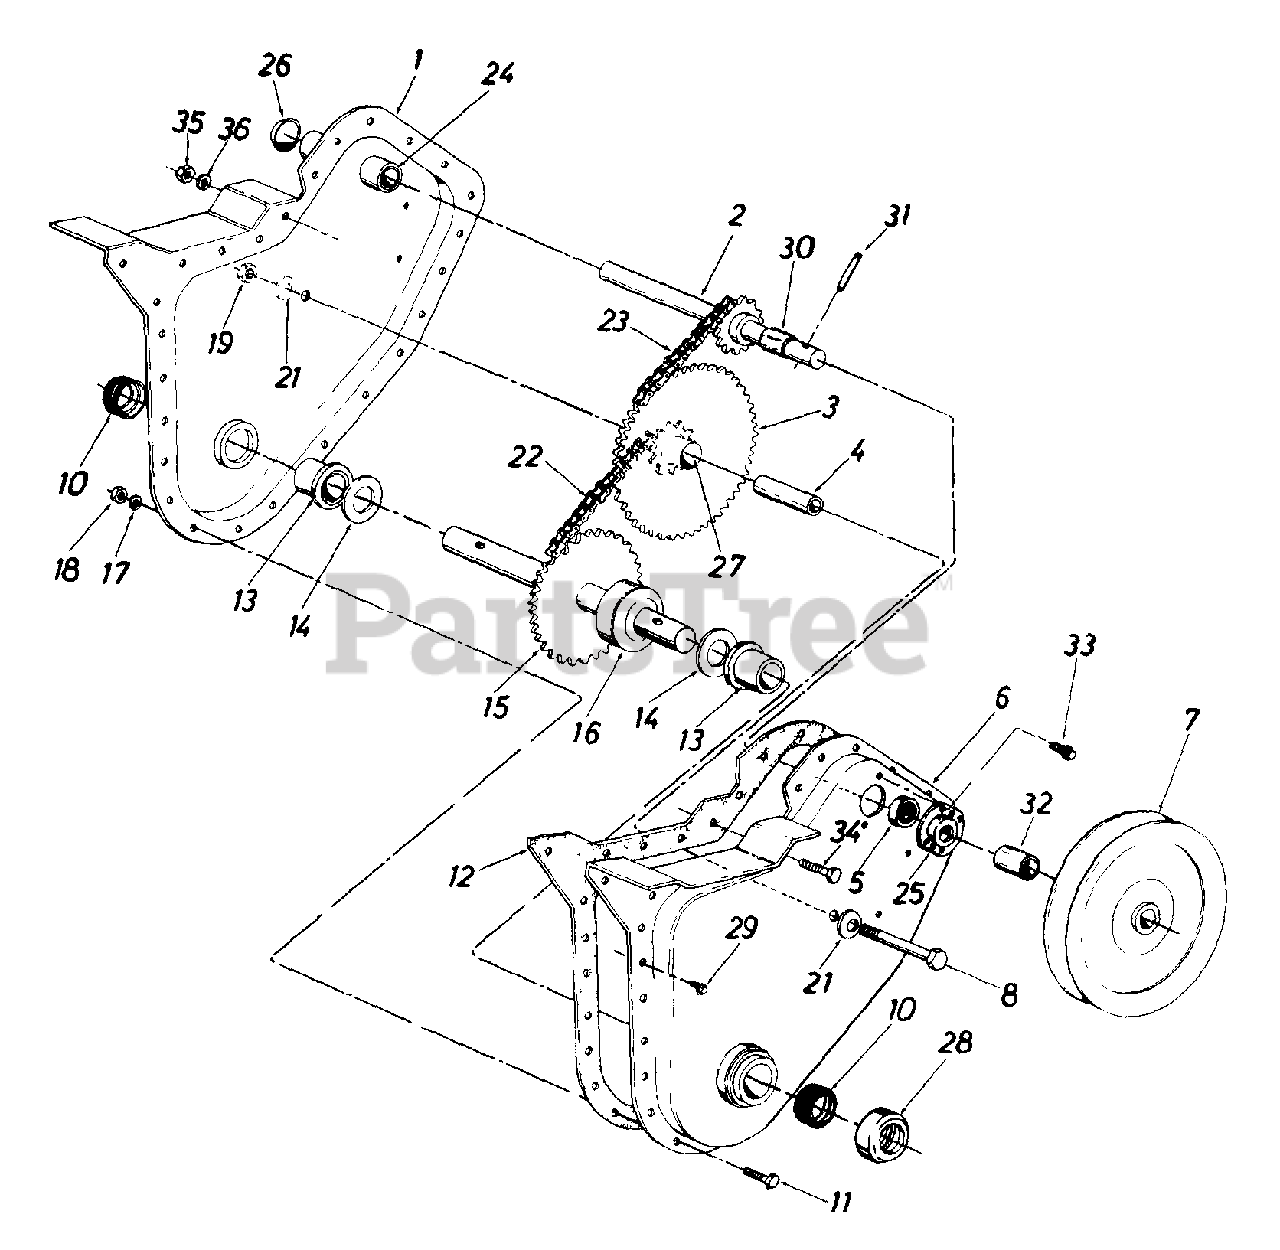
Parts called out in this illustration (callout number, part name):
1	Chain Case Ass'y.- R.H.
2	Input Shaft Ass'y.
3	Hub and Sprocket Ass'y.
4	Bearing Inner Race
5	Ball Bearing
8	Hex Bolt 3/8-24 x 2.5"
10	Seal
11	Hex Bolt 1/4-28 x .625"
12	Gasket
13	Flange Brg. .879" I.D.
14	FI-Wash. .88" I.D. x 1.5"
15	Tine Shaft Ass'y.
16	Spacer 7/8" l.D.
17	L-Wash. 1/4" I.D.
18	Hex Nut 1/4-28 Thd.
19	Hex Ins. L-Nut 3/8-24 Thd.
21	Bell-Wash. .406" I.D.
22	Chain #420 1/2" Pitch 38 Links
23	Chain #35 .375" Pitch 50 Links
24	Bearing .62" I.D. x .813"
25	Bearing Housing
26	Expansion Plug 13/16" Dia.
28	Dust Cap
29	Hex Wash. Hd. Self-Tap Scr. 1/4-20 x .50" Lg.
30	Spacer .63" I.D. x .77" O.D.x .38" Lg.
31	Spring Pin Spiral 1/4" Dia x 1-1/2" Lg.
32	Spacer .647 x 1.25"
33	Hex Wash. Hd. Self-Tap Scr. 1/4-20 x .38" Lg.
34	Hex Bolt 5/16-18 x .75" Lg.
35	Hex Nut 5/16-18 Thd.
36	L-Wash. 5/16" I.D
